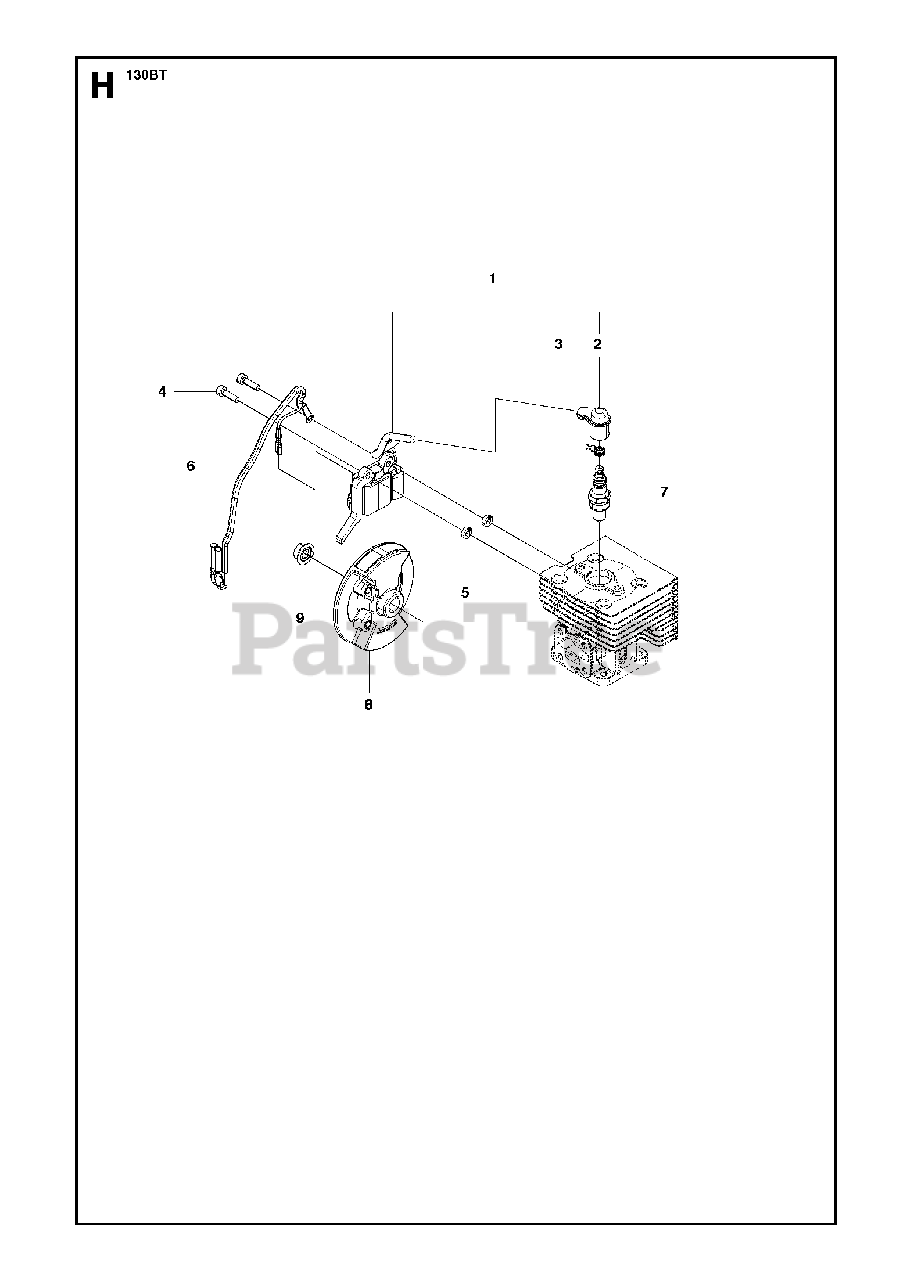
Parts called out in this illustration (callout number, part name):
2	CAP
3	SPRING
6	CORD-COMPL.
7	SPARK PLUG NGK CMR7H
9	NUT
